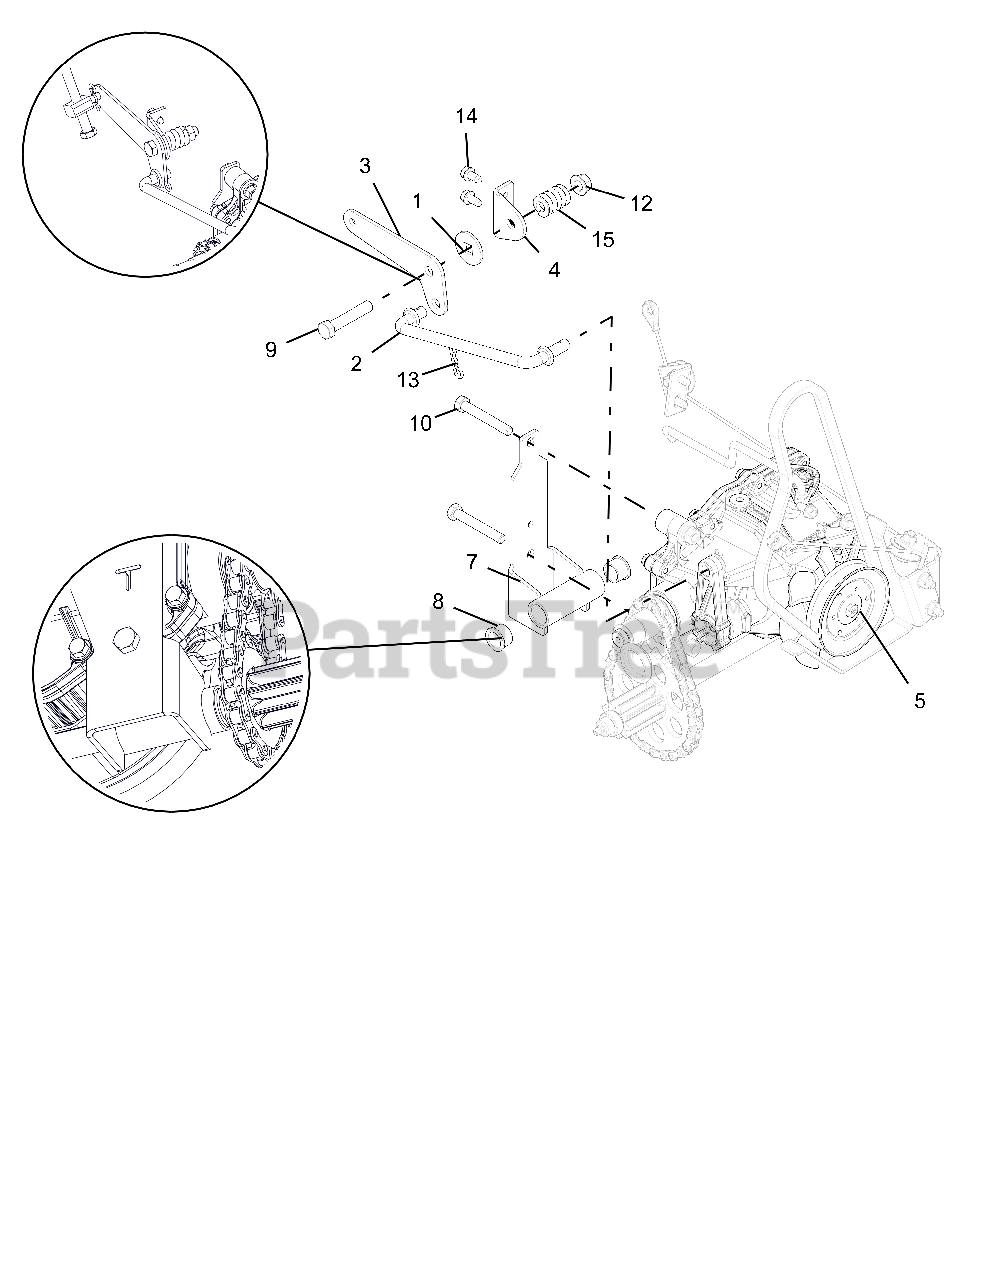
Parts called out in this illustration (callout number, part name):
1	FRICTION WASHER
2	ROD, HYDRO TRANS SHIFT
3	PIVOT, HYDRO TRANS SHIFT
4	BRACKET, HYDRO SHIFT PIVOT
5	TRANSMISSION, HYDROSTATIC
7	TRANS MOUNT, TENSIONING, WHEEL
8	BSHG-FLG .625X.750X.500X.875
9	@BLT-HEX .38-16X2.00 GR5 YWZC
10	@BLT-HEX .31-18X2.25 GR5 YWZC
12	@NUT-LK-TOP-FLG .38-16 YWZC
13	PIN-HAIR INT .08X.18X1.18 YWZC
14	SCR-TAP .25-20X.50 HWH TR YWZ
15	SG-COMP .187X.56X1.62
